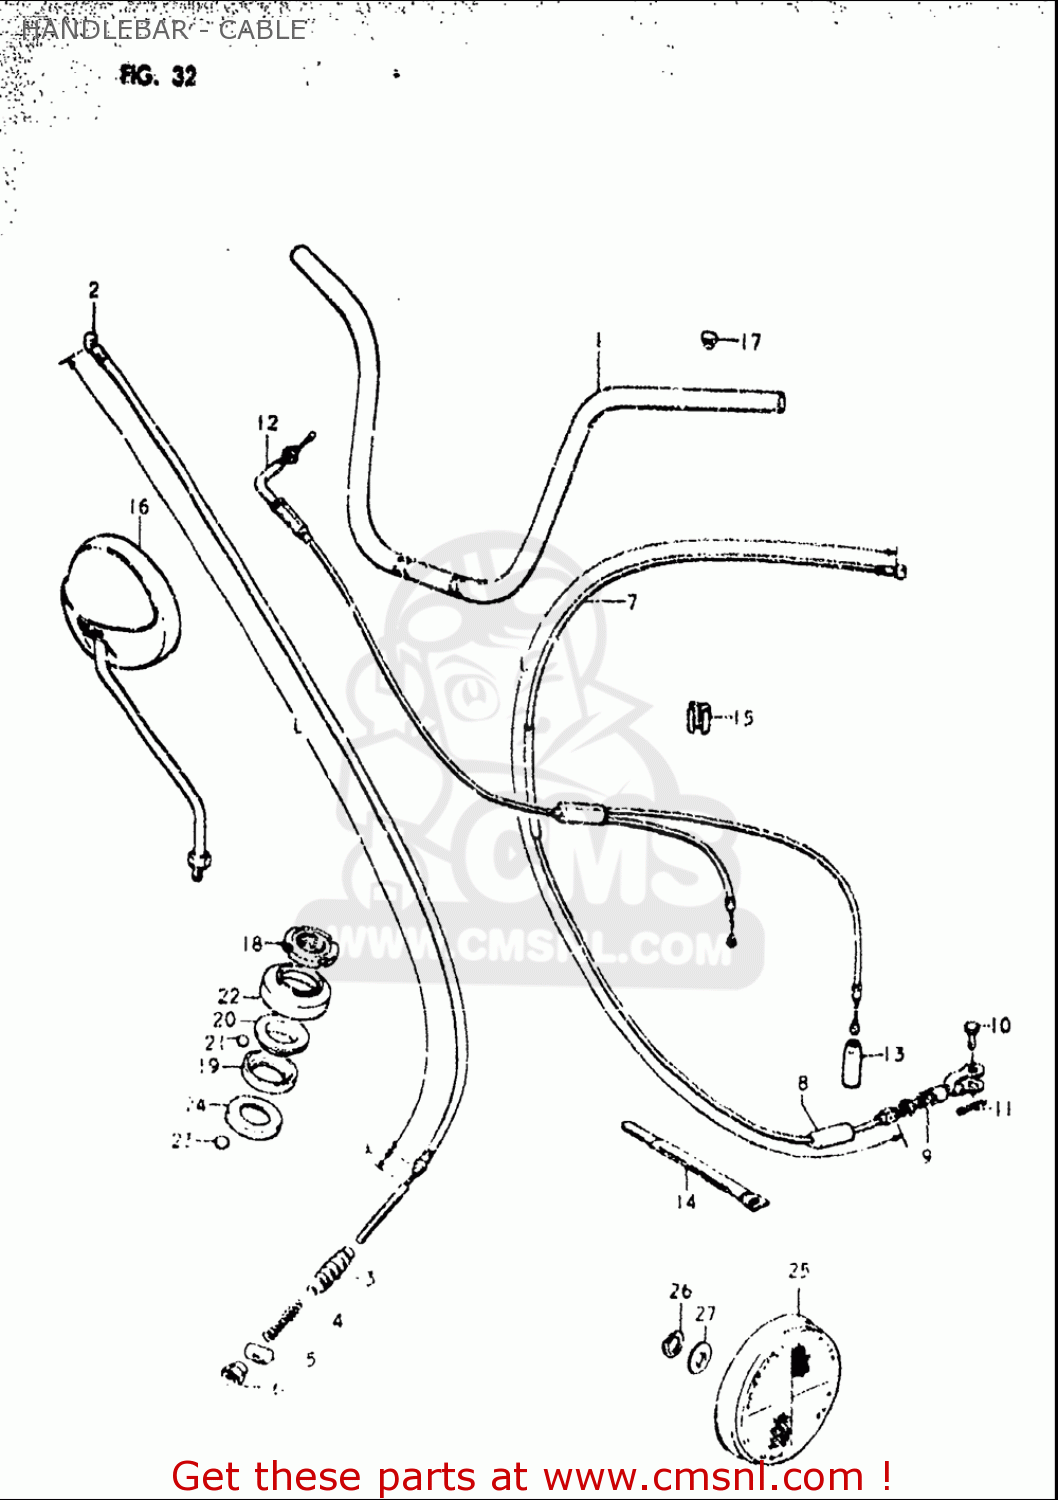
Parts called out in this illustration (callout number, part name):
2	CABLE ASSEMBLY,FRONT BRAKE
3	SEAL,DUST(7X16X75)
4	SPRING
5	BRAKE ROD LEVER
6	BRAKE ROD ADJ N
7	CABLE ASSY,CLUTCH
8	SEAL,DUST(7X18X30)
9	NUT
10	PIN(L:13)
11	PIN
12	CABLE ASSY,THROTTLE
13	SEAL,DUST(7X18X30)
14	CLAMP
15	CLIP
17	CAP
18	NUT,STEERING STEM(25X44X10)
19	RACE,STEERING INNER UPR
20	RACE,STEERING OUTER UPR
21	BALL
22	STEERING DUST S
23	BALL
24	LACE,STEERING INNER LWR
25	REFLEX REFLECTOR,FR
26	WASHER,LOCK
27	WASHER
